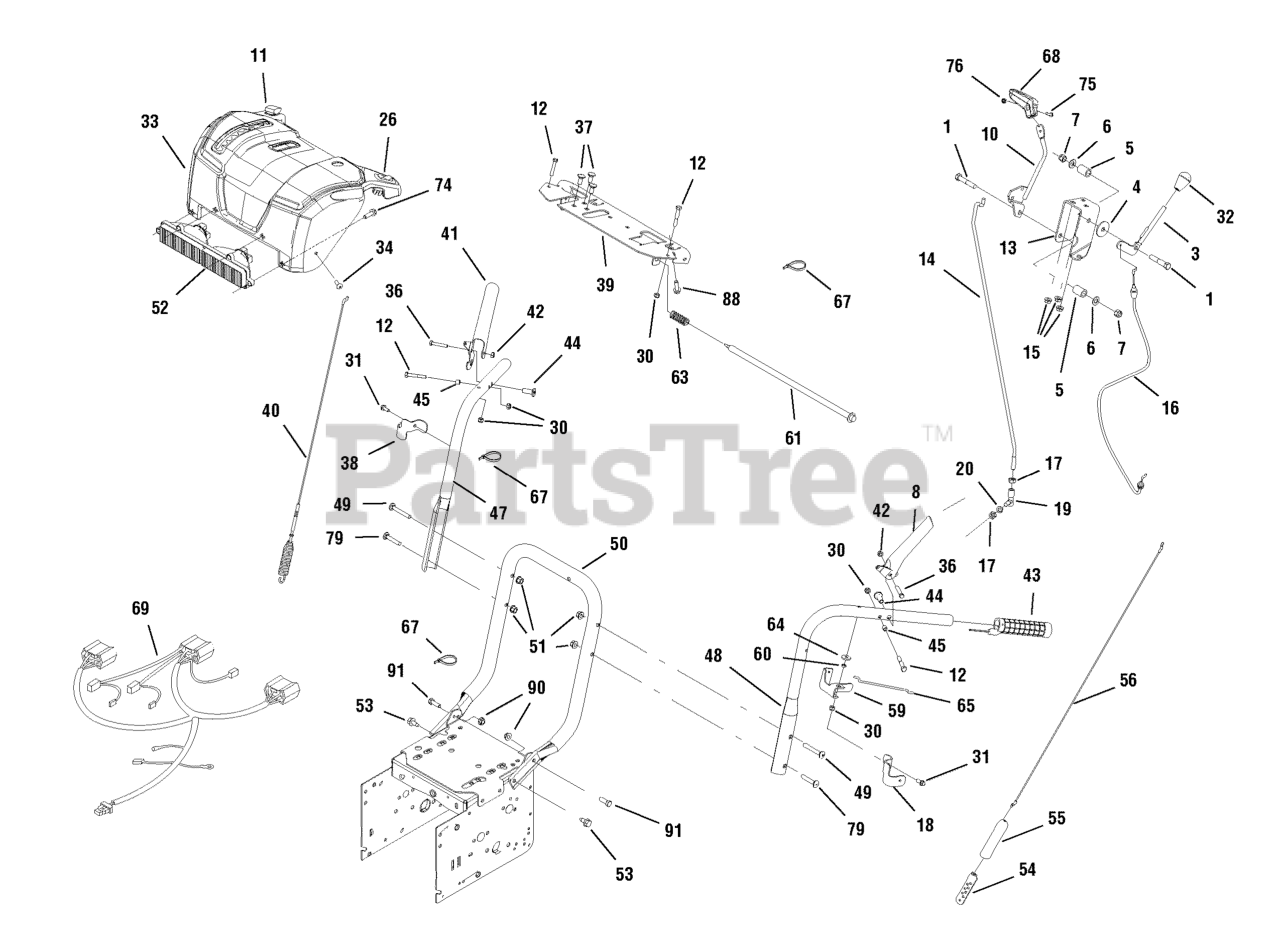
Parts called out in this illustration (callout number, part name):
1	CAPSCREW-HEX. 375 - 16x2.00
3	LEVER-DEFLECTOR CONTROL
4	WASHER- 0.375 0.4 1x 1.50 x .12
5	SPRING- COMPRESSION .509 x .75 2
6	WASHER- O. 375 O. 4 1 x 0.8 1 x .06
7	NUT -HEXLK ESNA LT . 38- 16NC3B
8	LEVER-CLUTCH LH PLASTISOL DIP
10	LEVER ASSEMBLY-SPEED
11	SWITCH, CHUTE CONTROL
12	CAPSCREW-HEX .250- 20 x 1 . 75
13	BRKT- SPEED & DEFLECTOR CONTROL
14	ROD-LINK SPEED CONTROL
15	NUT-HEX FLANGE . 3 12- 18 WHIZ
16	CABLE ASSEMBLY-DEFLECTOR
17	NUT-HEX . 3 12- 24 YEL LOW
18	MNTG BRKT - DASH LH
19	BALLJOINT-STEEL
20	LOCKWASHER - SPRING . 312 BLK
26	SWITCH, HAND WARMER
30	NUT-HEX LOCK ESNA .250-20
31	SCREW-HEX WSHR HD TT .25- 20x. 62
33	COVER-PANEL ASS'Y
34	SCREW-PAN HD TR x . 250-20 x .75 TAP
36	CAPSCREW- HEX .2 50 -20 x 1 .50
37	BOLT, Carriage, 5/16-18 x 3/4
38	MNTG BRKT - DASH RH
39	SUPPORT-DASH PANEL
40	CABLE & SPRING ASSEMBLY
41	GRIP-CLUTCH-RH PLASTISOL
42	NUT-HEX CTR LOCK. 250- 20 BLK
43	HAND GRIP- HEATED
44	SPACER- HANDLE-YELLOW
45	SPACER- 0.265x0.370x.330
47	HANDLE-UPPER RH
48	HANDLE-UPPER LH
49	BOLT-RD HD SO NK .312-18x2.25
50	HANDLE-LOWER
51	NUT-HEX FLANGE.312-18 ESNA
52	HEAD LIGHT ASSEMBLY
53	SCREW-HEX WSHR HD TT .31-18x.75
54	BRACKET-CABLE ADJ
55	BOOT-CONTROL SPRING
56	CABLE-DRIVE
59	BRACKET-FREE HAND CONTROL
60	SPACER-PWDR METAL YELLOW
61	ROD-FREE HAND CONTROL
63	SPRING-COMP.53x2.25 .059 WIRE
64	WASHER-.250.26x0.84x.12
65	ROD-HOLDDOWN
67	TIE-SELF LOCKING .184WDx7.31
69	HARNESS, WIRE HEATED GRIPS, CHUTE ROTATE
74	SCREW 10-16 x.5 HI/LO HEX WSH HD TAP
75	SCREW-RD HD PHIL 1/10-24 x.75
76	NUT-HEX ESNA LOCK 10-24
79	BOLT-RD HD SH SO NK .312-18x1.75
88	SCREW, 1/4-15X3/4, Self-Tapping, BZ
90	NUT-HEX FLANGE .31-18 2-WAY LK
91	CAPSCREW, Hex Head, 5/16-18 x 1
